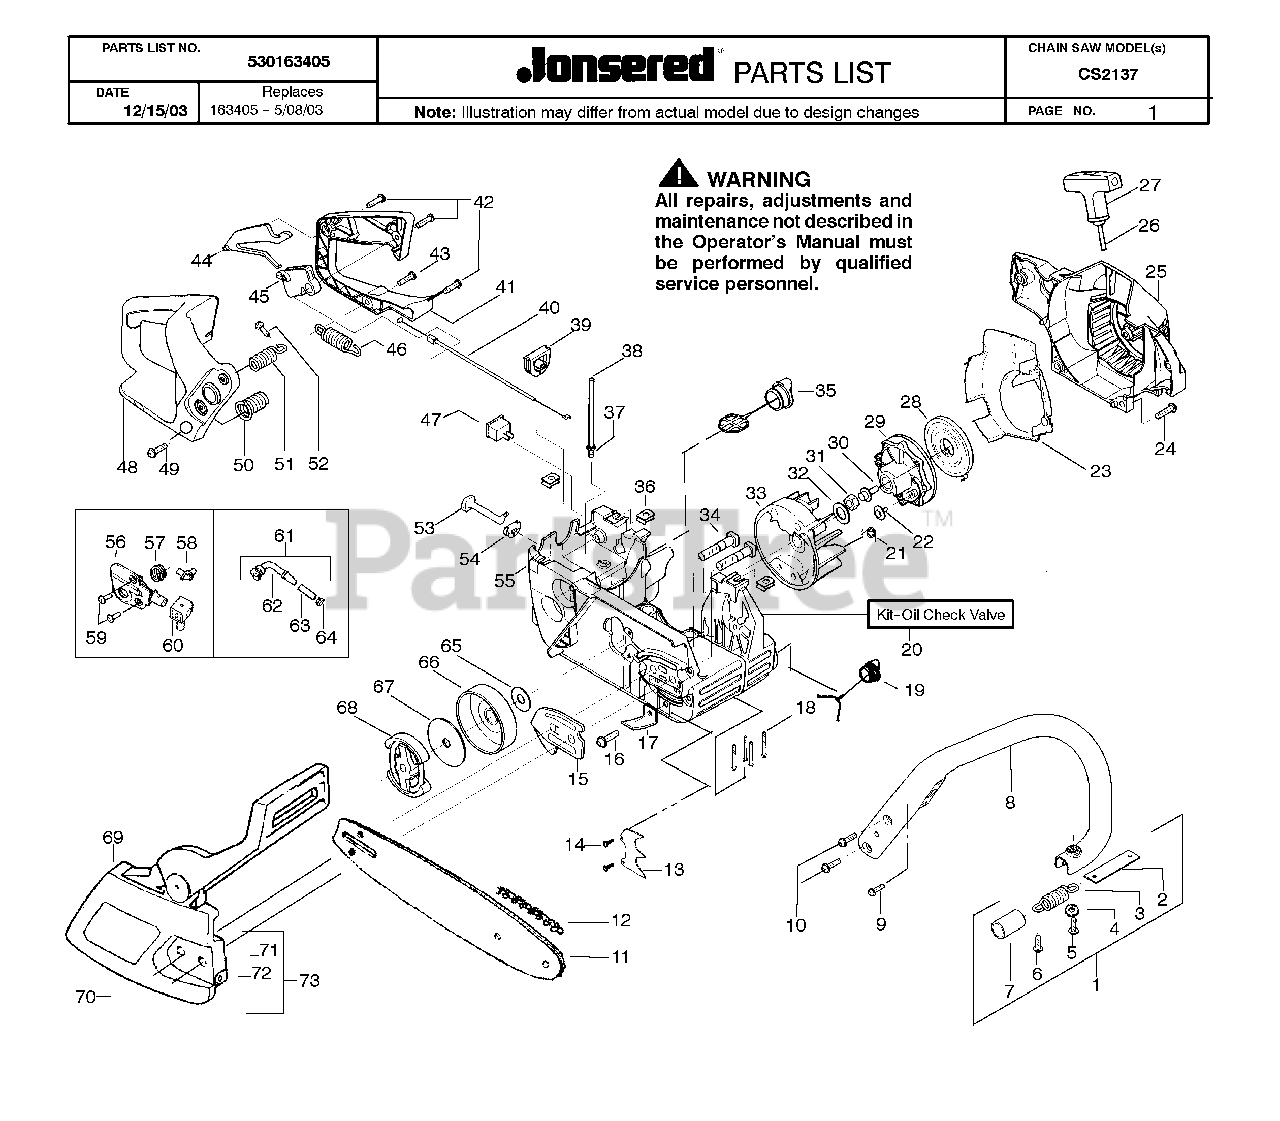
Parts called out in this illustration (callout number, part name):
1	ASSY-ISOLATOR
2	STRAP
3	SPRING
8	HANDLE
13	SPIKE 36/41
14	SCREW-10-16 X 1/2, TYPE 2
17	CHAIN CATCHER 36/41
19	OIL TANK CAP
20	KIT-OIL CHECK VALVE
21	SPRING STR DOG
23	AIR BAFFLE
24	SCREW,STRTR CVR 36/41
27	HANDLE STARTER
29	STARTER PULLEY
31	NUT-FLYWHEEL
32	WASHER-FLYWHEEL
33	FLYWHEEL ASS'Y
35	TANK CAP
37	FUEL LINE FITTING
40	THROTTLE WIRE
42	SCREW,FRONT HBAR 36/41
43	SCREW-10-14 X 13/16 (PL
44	THROTTLE LOCK
45	THROTTLE TRIGGER
46	SPRING
50	SPRING
51	SPRING
57	WORM GEAR
62	PICK-UP OILER
63	FILTER
64	PLUG
65	DUST COVER 36/41
66	CLUTCH DRUM ASSY
67	FRICTION DISC,CLUTCH 36/41
68	CLUTCH ASSEMBLY
71	ADJUST PIN,BAR 36/41
